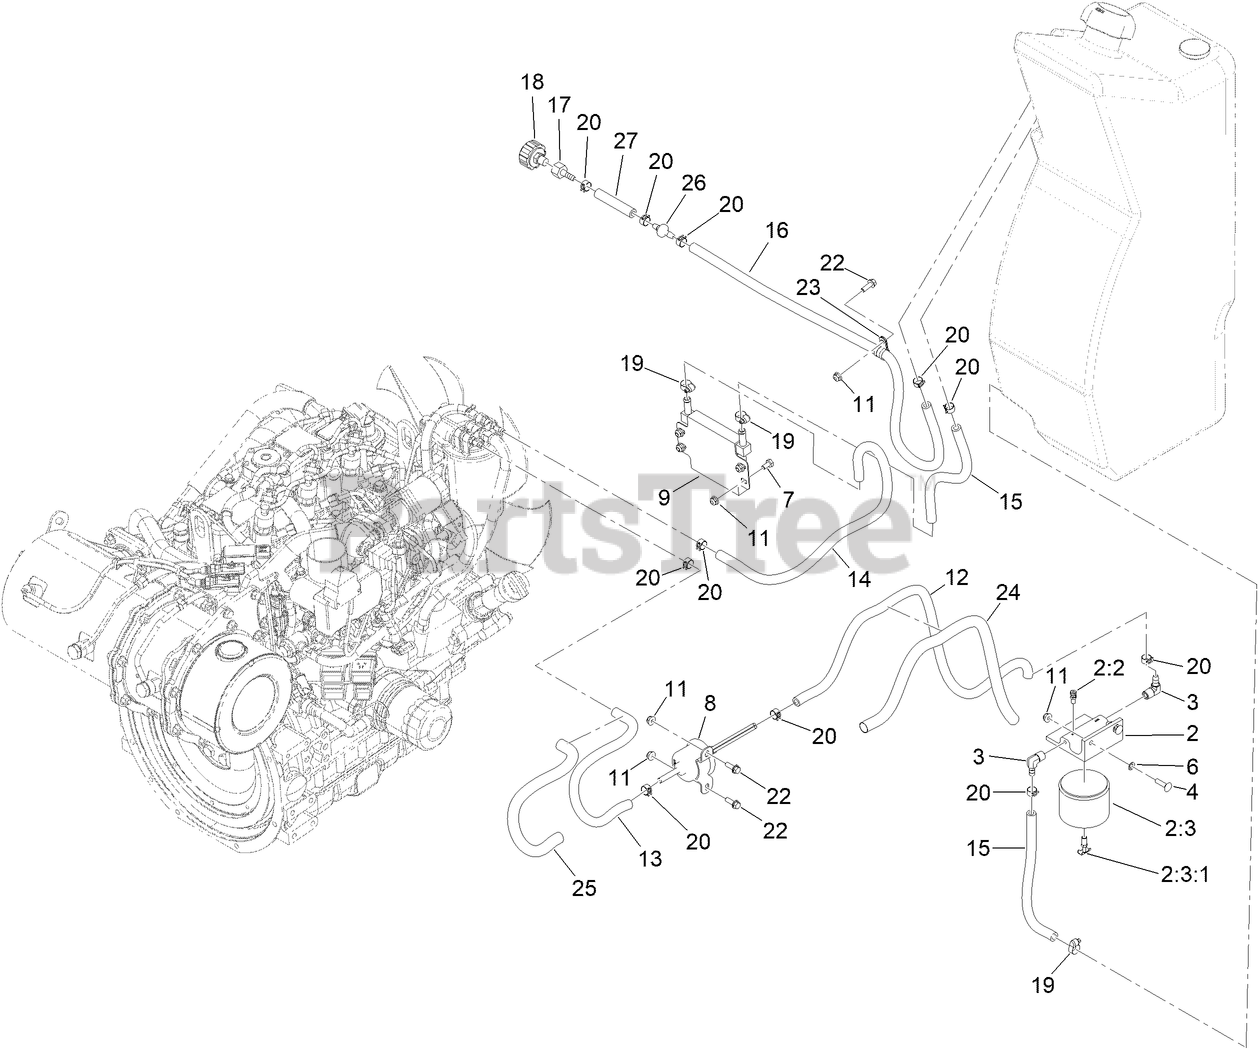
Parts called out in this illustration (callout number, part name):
2	FILTER HEAD ASM
2:2	VENT-AIR
2:3	ELEMENT-SPIN ON
2:3:1	VALVE-DRAIN
3	FITTING-HYD, 90
4	SCREW-CARR
6	NUT-RETAINING
7	SCREW-HH
8	PUMP-FUEL, ELECTRIC
9	COOLER-OIL
11	NUT-HF
12	HOSE-FUEL
13	HOSE-FUEL
14	HOSE-FUEL
15	HOSE-FUEL
16	HOSE-FUEL
17	FITTING-STRAIGHT
18	BREATHER
19	CLAMP-WORM
20	CLAMP-HOSE
22	SCREW-HHF
23	CLAMP-R
24	SLEEVE-THERMAL
25	SLEEVE-THERMAL
26	VALVE-CHECK, FUEL
27	HOSE-FUEL
